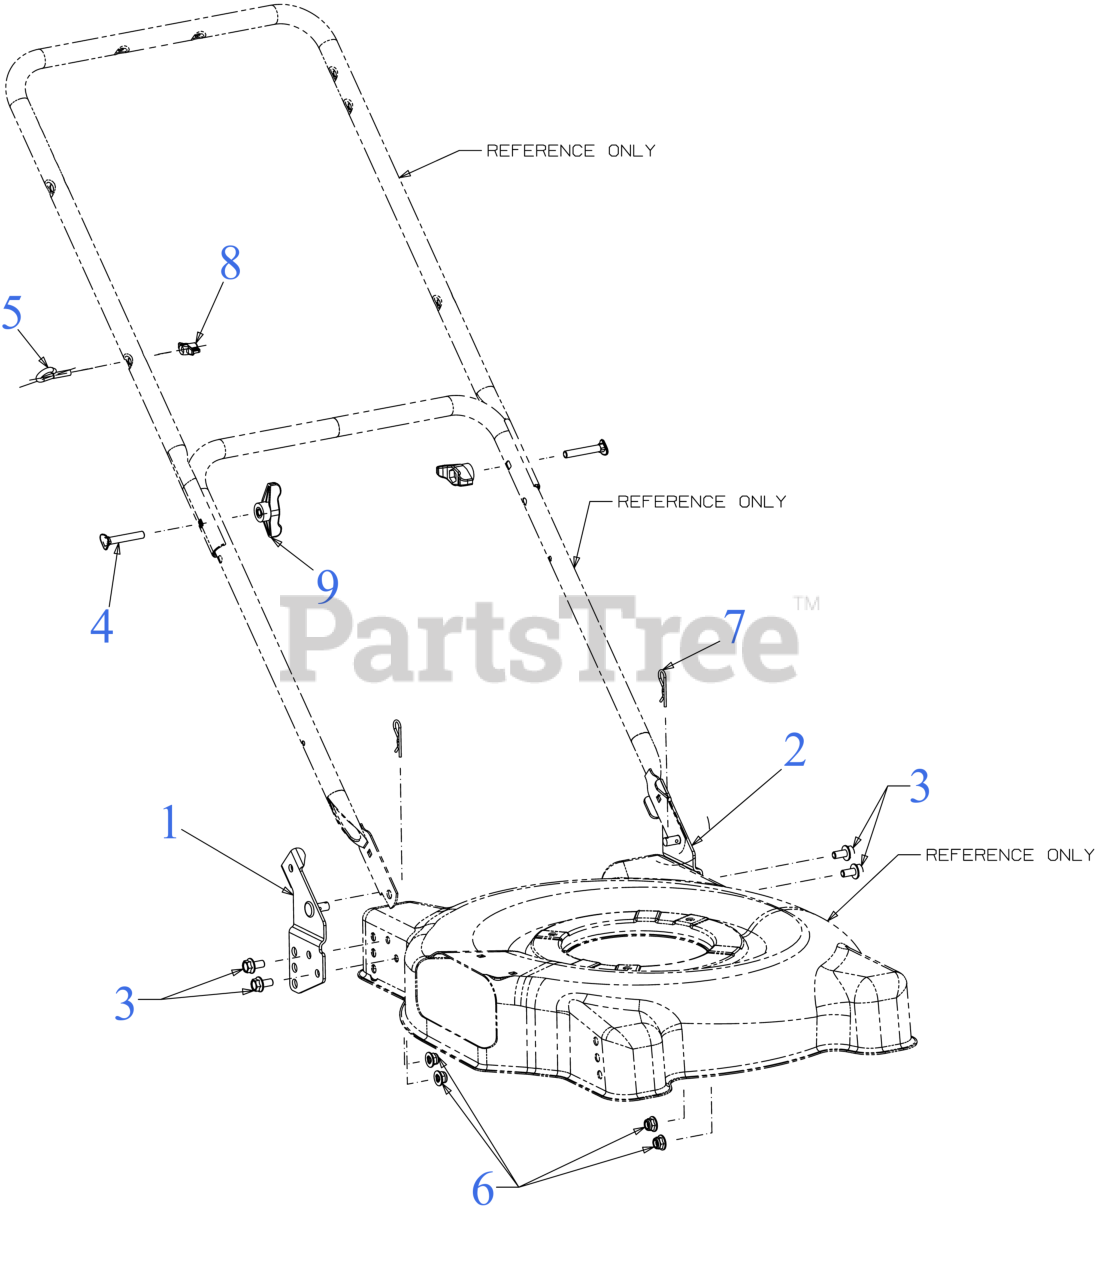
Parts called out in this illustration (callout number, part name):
1	HANDLE BRACKET ASSEMBLY (RH)
2	HANDLE BRACKET ASSEMBLY (LH)
3	SCREW 5/16-18 x .625 GR5
4	SCREW .312-18X2.0
5	EYEBOLT 1/4-20
6	FLANGE LOCK NUT 5/16-18
7	INTERNAL COTTER PIN
8	HANDLE KNOB
9	WING KNOB 5/16-18
